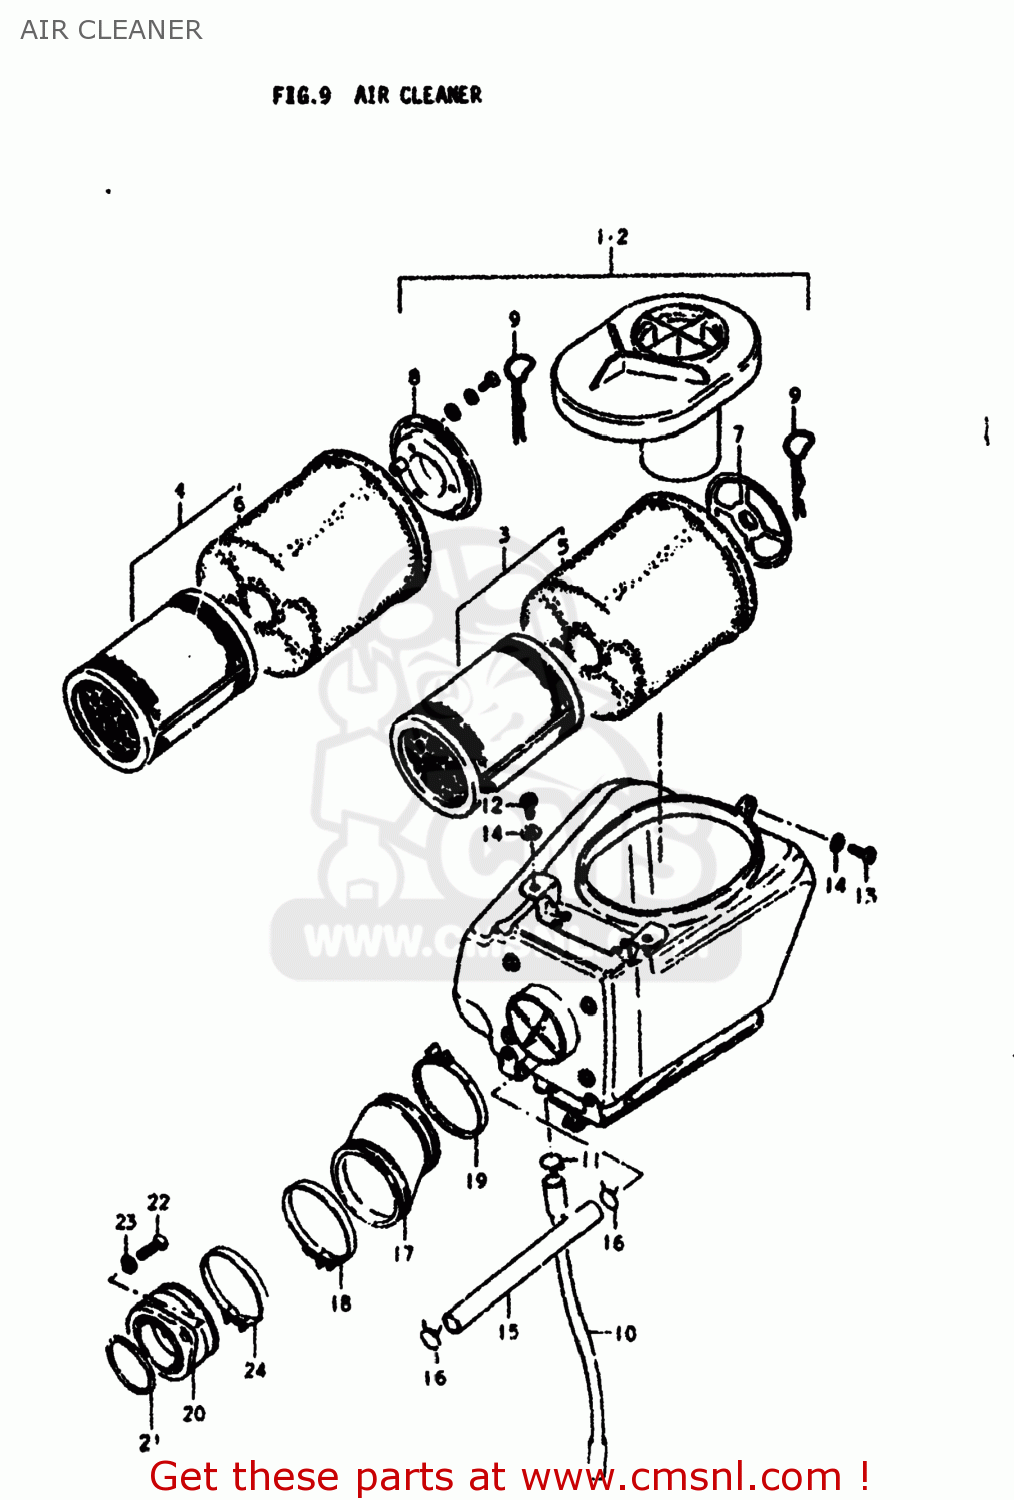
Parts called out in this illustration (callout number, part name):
1	CLEANER ASSEMBLY,AIR
2	CLEANER ASSEMBLY,AIR
3	FILTER,AIR CLEANER
4	FILTER,AIR CLEANER
5	ELEMENT,AIR CLEANER
6	ELEMENT,AIR CLEANER
7	HOLDER,FILTER
8	HOLDER,FILTER
9	SPRING,AIR CLEANER
10	HOLDER,FILTER
11	HOSE,AIR CLEANER
12	SCREW
13	SCREW
14	WASHER 6MM
15	HOSE
16	CLIP
17	TUBE,AIR CLEANER OUTLET
18	CLAMP
19	CLAMP
20	PIPE,INTAKE
21	O-RING (D:2.4 ID:39.7)
22	SCREW
23	LOCK WASHER
24	CLAMP
